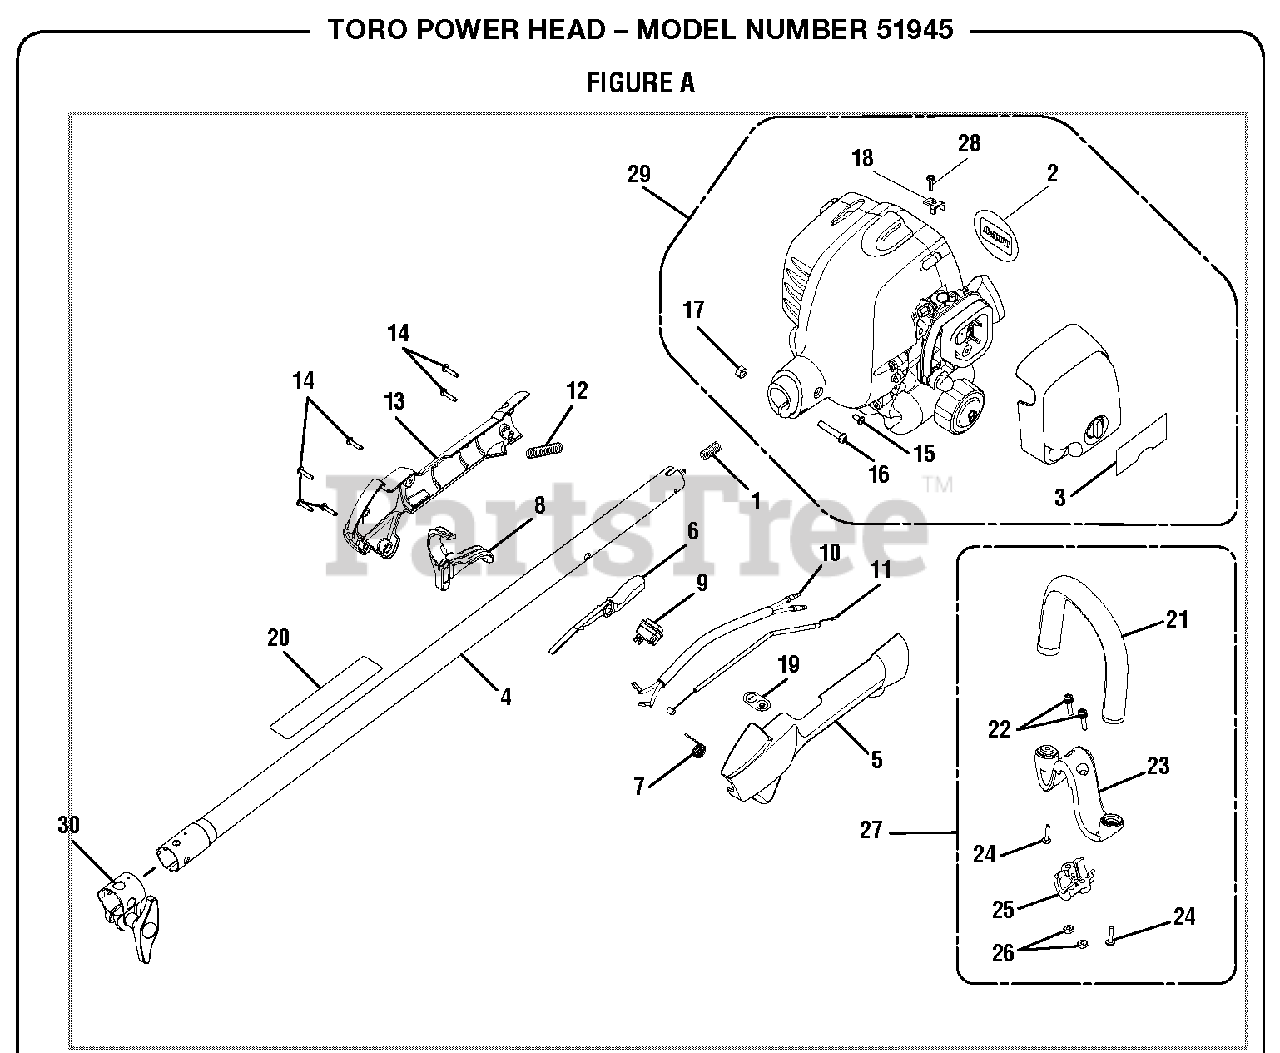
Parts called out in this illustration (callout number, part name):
1	Compression Spring
2	Logo Plate
3	Lower Start Label
4	Upper Shaft Assembly
5	Rear Handle Support
6	Lock-off Button
7	Trigger Spring
8	Trigger
9	On/Stop Switch
11	Throttle Cable
12	Corrugated Tube
13	Rear Handle Cover
14	Screw (M4 x 16 mm)
15	Screw (#8-16 x 1/2 in., Tri-Lobular)
16	Screw (M6 x 1-30 mm)
17	Hex Nut (M6.3 x 1)
18	Throttle Cable Clamp
19	On/Stop Label
20	Warning Label
21	Front Handle w/Grip
22	Screw (#12-24 x 1 in., Slotted Torx)
24	Screw (10-14 x 1 in.)
25	Clamp
26	Hex Nut (12-24)
27	Front Handle Assembly
28	Screw (M4 x 16 mm)
29	Powerhead Assembly
30	Boom Clamp
